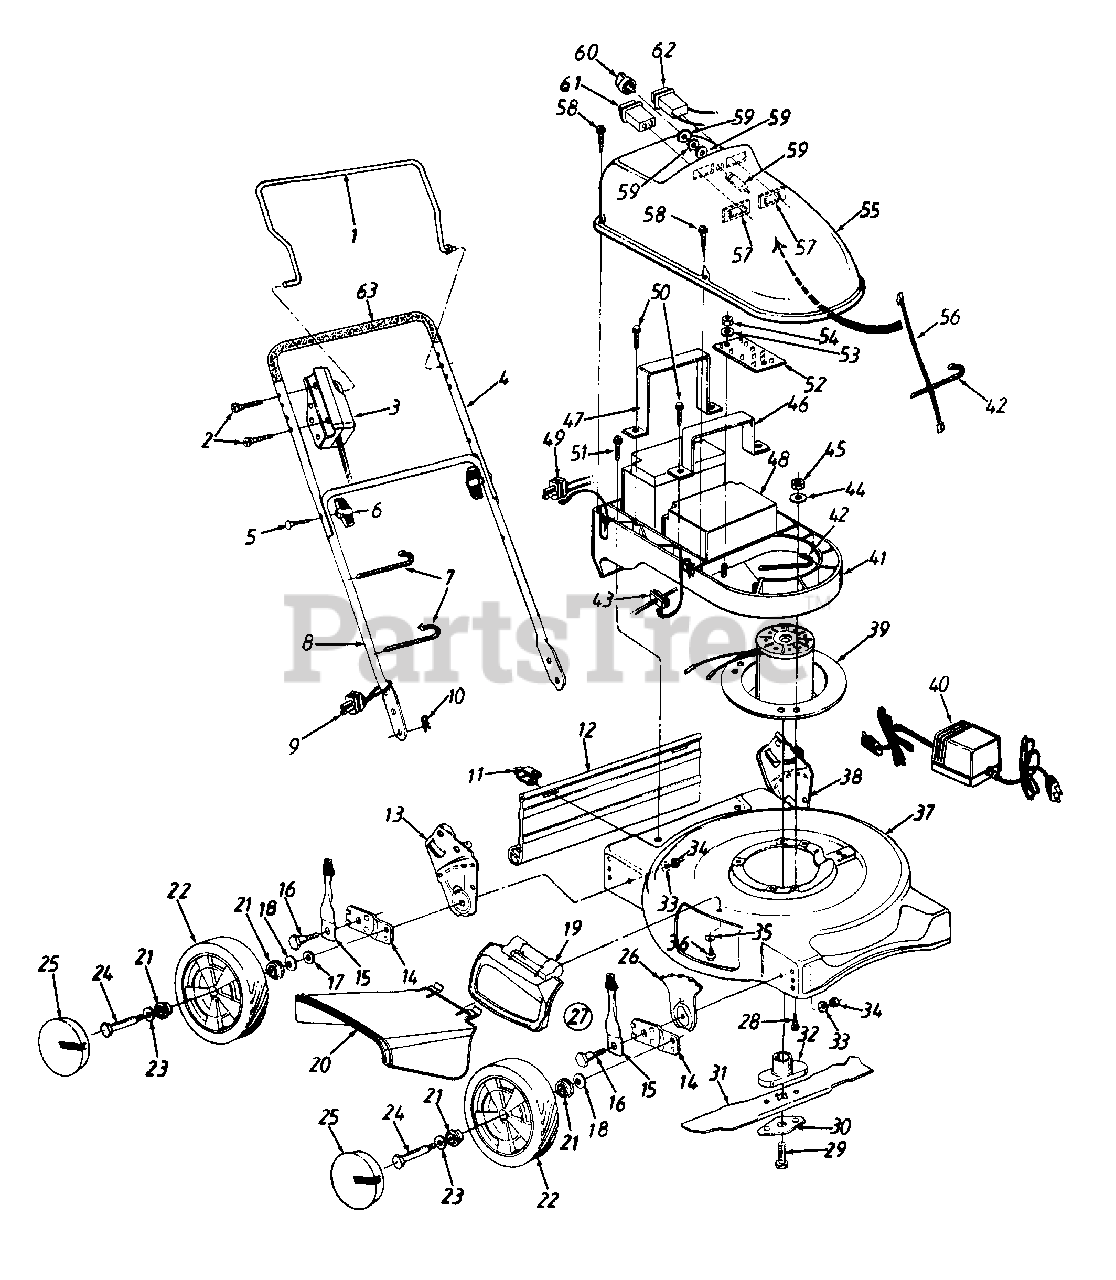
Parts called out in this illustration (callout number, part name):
3	Switch Ass'y.
6	Handle Knob
7	Cable Tie
9	Plug
10	Hairpin Clip
11	Hinge Clip
12	Rear Flap
13	Handle Brkt. Ass'y.-R.H.
15	Spring Lever Ass'y. w/Knob
16	Shld. Bolt .5" Dia. x .43" Lg
17	FL-Wash. .385" I.D. x 1" O.D.
18	Bell-Wash. .38" I.D. x .88" O.D.
19	Mulching Plug Ass'y.
20	Chute Deflector
21	Ball Bearing
22	Wheel Ass'y.
23	Wave Wash. .51" I.D. x .75" O.D.
24	Shld. Bolt .598" Dia. x 1.45
25	Hub Cap
26	Height Adj. Plate
27	Height Adj. Ass'y. Comp.-R.F.
28	Hex Wash. Self-Tap Scr. 3/8-16 x 1" Lg.
29	Hex Bolt 3/8-24 x 2.5" Lg.
30	Blade Bell Support
31	18" Blade
32	Blade Adapter
33	Bell-Wash. .39" I.D. x 1.38" O.D.
34	Hex Nut 3/8-16 Thd.
35	Bell-Wash. 1/4" I.D.
36	Hex Wash. Hd. TT-Tap Scr. 1/4 x .5" Lg.
39	Motor Ass'y.
40	Charger
41	Tray Ass'y.
42	Cable Tie
43	Harness Ass'y. Switch
44	FL-Wash. .406" I.D.
45	Hex L-Nut 3/8-16 Thd.
46	Front Bracket Ass'y.
47	Rear Bracket Ass'y.
48	Battery Ass'y.
49	Charger Plug
50	Hex Hd. Hi-Lo Scr. 1/4 x .75" Lg.
51	Hex Wash. Hd. Tt-Tap Scr. 1/4-20 x 1" Lg.
52	Circuit Board
53	FL-Wash. .21" I.D. x .56" O.D.
54	Palnut Self-Threading
55	Motor Cover
56	Key Switch Harness Ass'y.
57	Mounting Clamp
58	Hex AB-Tap Scr. #10 x .75" Lg.
59	Key Switch
61	Meter
62	Meter
63	Foam Grip
